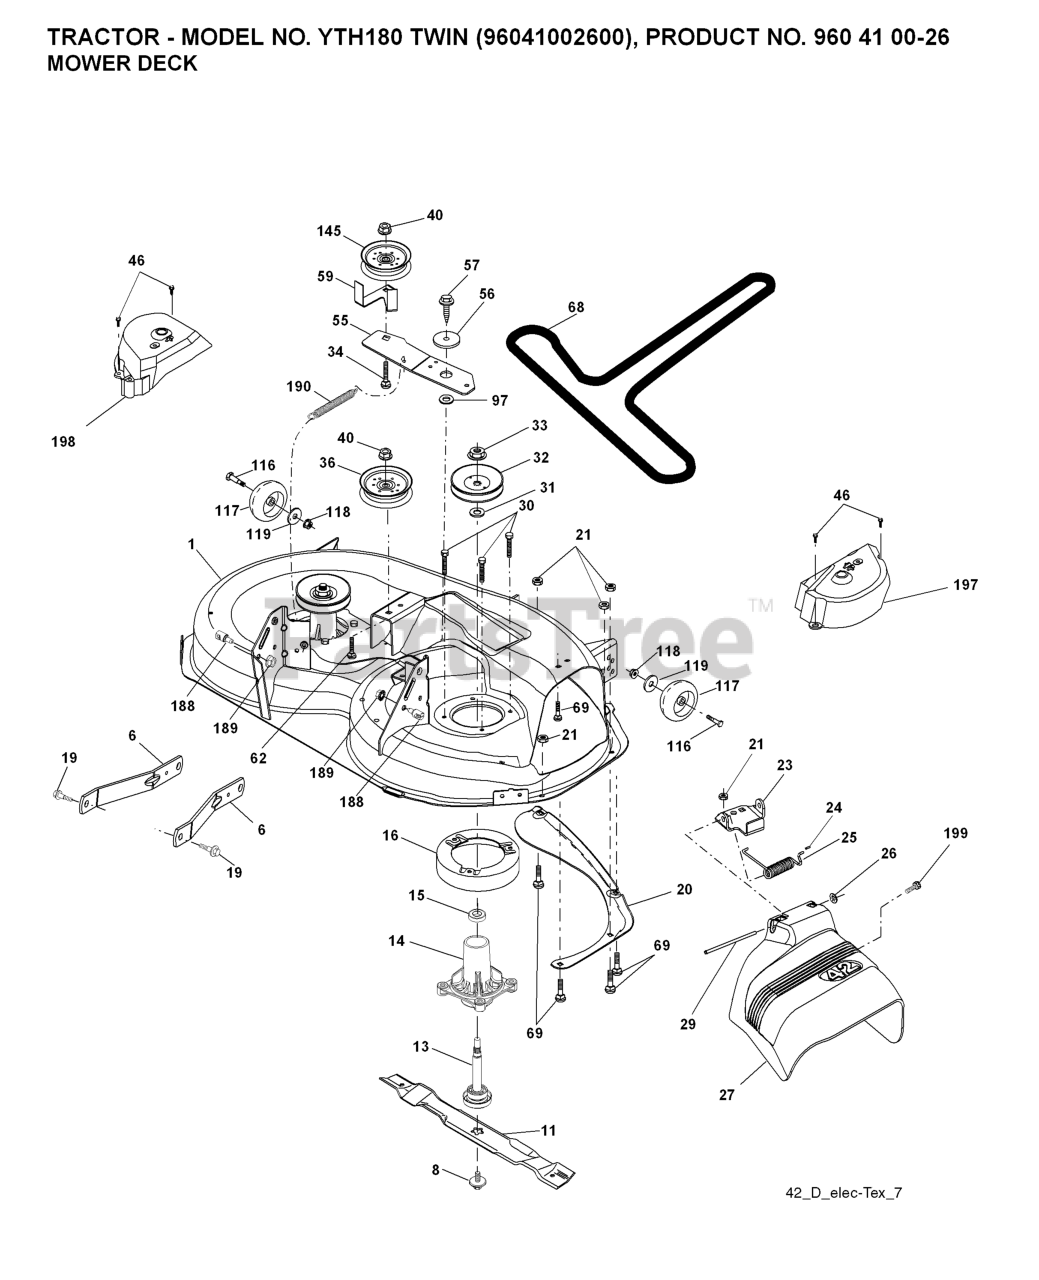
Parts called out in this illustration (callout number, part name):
1	DECK.WELDMENT.42"
6	ARM.SUSPENSION.MOWER.R
8	BOLT.WASHER.ASM.7/16-2
11	42" HI-LIFT BLADE
13	SHAFT.ASM.MDRL.N/GREASE.38
14	RP.HOUSING.MANDREL.4PT.
16	STRIPPER.MANDREL.ROUND.BLACK
19	BOLT.SHOULDER
20	BAFFLE.VORTEX
21	LOCKNUT
23	BRKT.DEFLECTOR.38"2005+
24	CAP-SLEEVE LT
25	SPRING.TORSION.DEFLECT
26	NUT PUSH M
29	ROD.HINGE
30	SCREW, WASHER HEAD
31	WASHER.SPACER.MANDREL
32	PULLEY/MANDREL
33	NUT.FLANGE.LOCK.TOP
34	BOLT.3/8-16X1.50
36	PULLEY.IDLER.48"PRIMARY
40	NUT LOCK FLG 3/8-16 UNC
46	SCREW.1/4-20X5/8
56	SPACER.RETAINER
57	SCREW 3/8-16X1
59	GUARD, BELT
61	SPRING EXT ELEC CLUTCH
68	BELT V SECONDARY
69	BOLT
116	BOLT M
117	WHEEL.GAGE.HALF.SPOKED
118	LOCKNUT
119	WASHER.5/16.FLAT.STE.STD.
145	PULLEY.IDLER.2006
188	STUD.FASTNER.W/ANTI-ROTATE
189	NUT LOCK HEX FLANGE 5/16-18
190	SPRING.MOWER.DRIVE.ELECTRIC
199	SCREW 3/8-16X1/2
